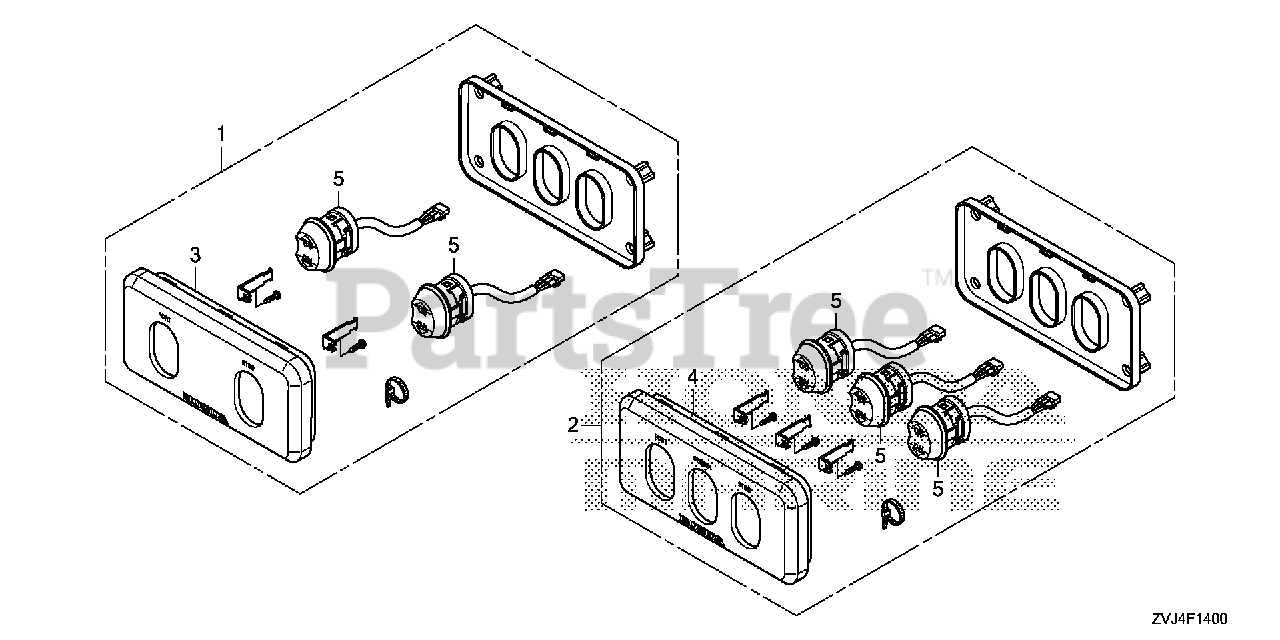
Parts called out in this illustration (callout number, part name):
1	PANEL ASSY., POWER TRIM-TILT SWITCH (TWIN)
3	PANEL, POWER TRIM-TILT SWITCH (TWIN)
5	SWITCH ASSY., POWER TILT
